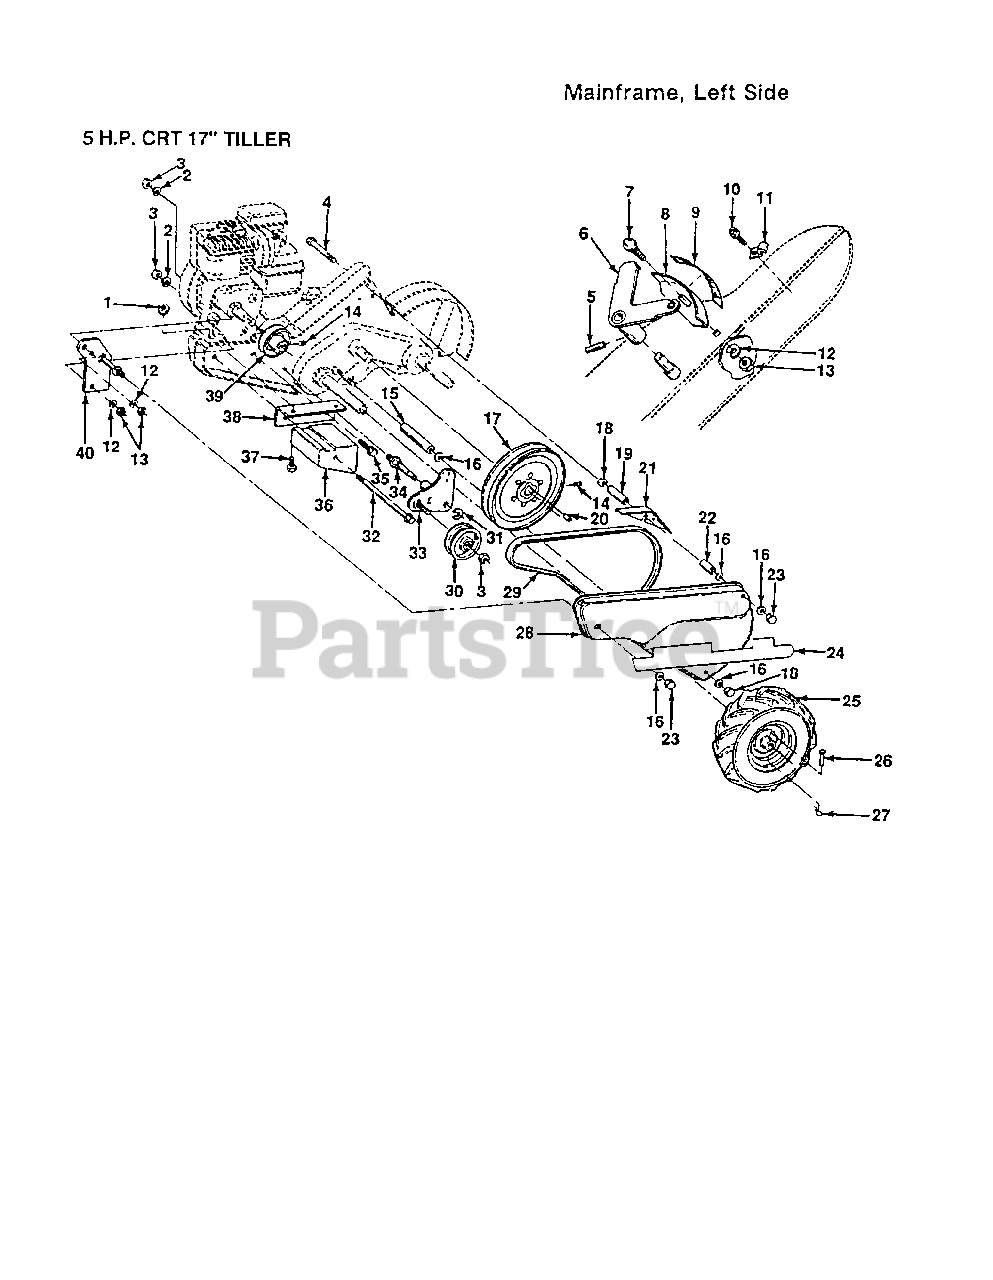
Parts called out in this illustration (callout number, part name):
2	LOCKWASHER
3	NUT.HEX.3/8-16UNC
4	BOLT-HEX TI
6	LEVER ASM CRT
7	BOLT
8	PANEL TI
11	CONDIUT CLIP T
12	LOCKWASHER
14	SET SCREW
15	SPACER
16	WASHER
17	"SHEAVE 10"" CRT"
18	NUT.HEX.5/16-18
19	SPACER CRT
20	KEY T
21	GUARD CRT
22	SPACER CRT
23	NUT TI
25	TIRE.CHV.13X5.0-6
27	RETAINER M
30	PULLEY-IDLER TI
31	KLIP RING
32	BOLT CRT
34	SHIFT ARM CRT
35	BOLT
36	COUNTERWEIGHT CRT
37	BOLT.HEX.5/16-1.5
38	BRACKET LH CRT
40	BRACKET ASSY CRT
